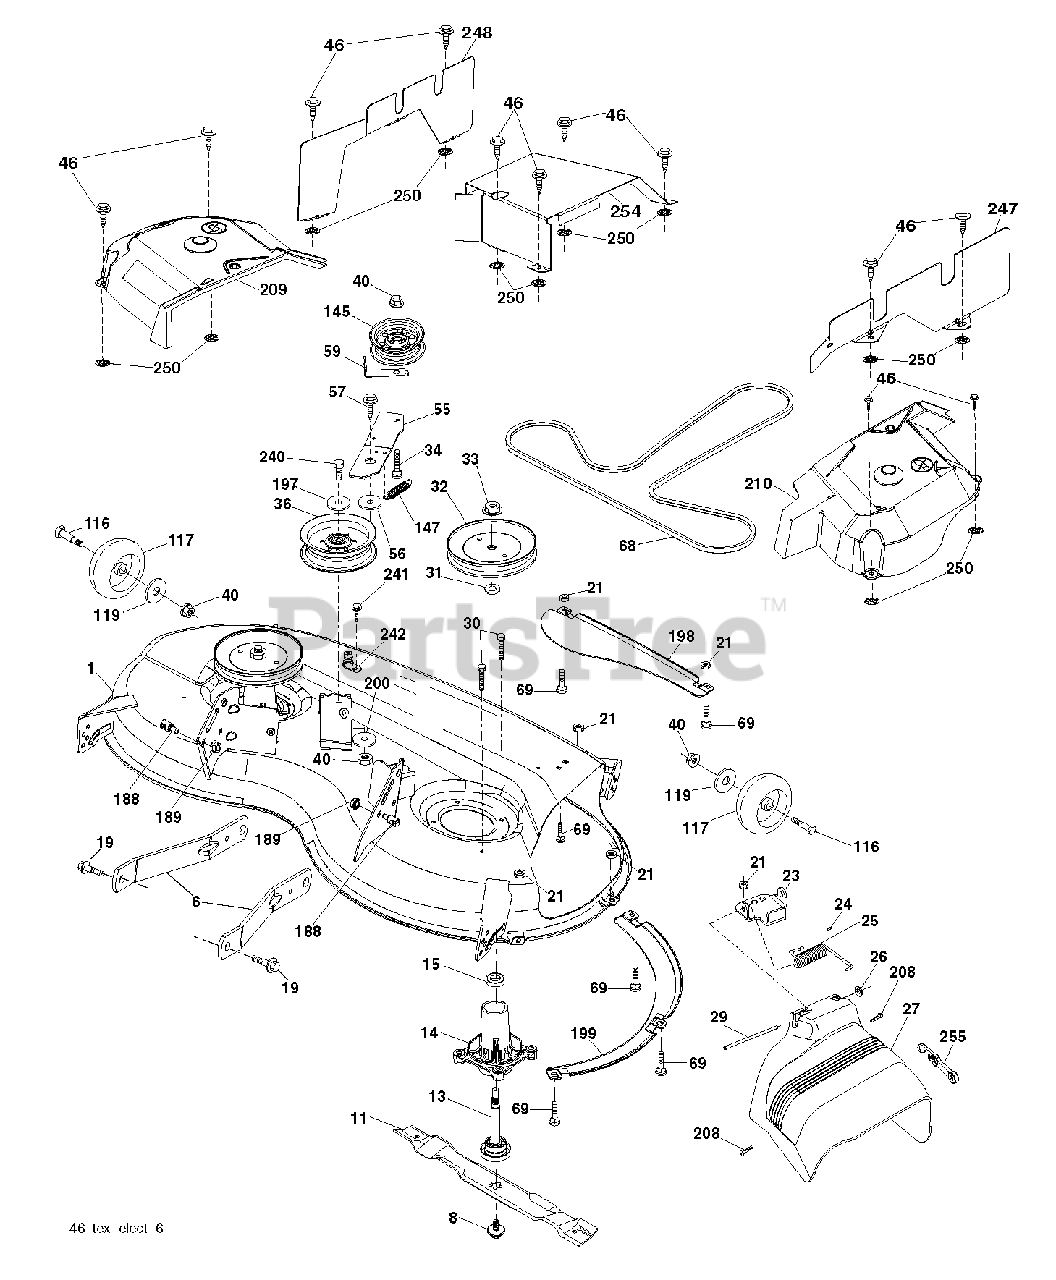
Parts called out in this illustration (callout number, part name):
1	DECK.WLDMT.W/TB.46.4GA.TTR
6	ARM.SUSPENSION.MOWER.R
8	BOLT.WASHER.ASM.7/16-2
11	BLADE.MOWER.46".HI.LIFT
13	SHAFT.ASM.MDRL.N/GREASE.38
14	HOUSING.MANDREL.4PT.
19	BOLT.SHOULDER
21	LOCKNUT
23	BRKT.DEFLECTOR.38"2005+
24	CAP-SLEEVE LT
25	SPRING.TORSION.DEFLECT
26	NUT PUSH M
27	SHIELD SUBASM DEFLECTOR 46 FRE
29	ROD.HINGE
30	SCREW, WASHER HEAD
31	WASHER.SPACER.MANDREL
32	PULLEY.MANDREL.5.438.PD
33	NUT.FLANGE.LOCK.TOP
34	BOLT.3/8-16X1.50
36	PULLEY.IDLER.2006
40	NUT LOCK FLG 3/8-16 UNC
46	SCREW.1/4-20X5/8
56	SPACER.RETAINER
57	SCREW 3/8-16X1
59	GUARD, BELT
68	V-BELT
69	BOLT
116	BOLT.SHOULDER.3/8-16X3-5/8.
117	WHEEL. GUAGE RALLY
119	WASHER
145	PULLEY.IDLER.48"PRIMARY
147	SPRING.MOWER.DRIVE.ELECTRIC
188	STUD.FASTNER.W/ANTI-ROTATE
189	NUT LOCK HEX FLANGE 5/16-18
197	WASHER
198	BAFFLE CENTER FRONT
199	BAFFLE FRONT RH
200	WASHER.13/32 X 1 X 1/2.11GUARD
208	SCREW 3/8-16X1/2
209	COVER MANDREL LEFT
210	COVER MANDREL RIGHT
240	BOLT-HEX EAK
241	SCREW.TT.#10-32X.5.3/8.FLANGE
242	PORT.WASHOUT
247	SHIELD RIGHT
248	SHIELD LEFT
250	PALNUT 1/4
254	SHIELD ASSEMBLY 46 TEX REAR DE
255	ELASTIC STRAP KIT
